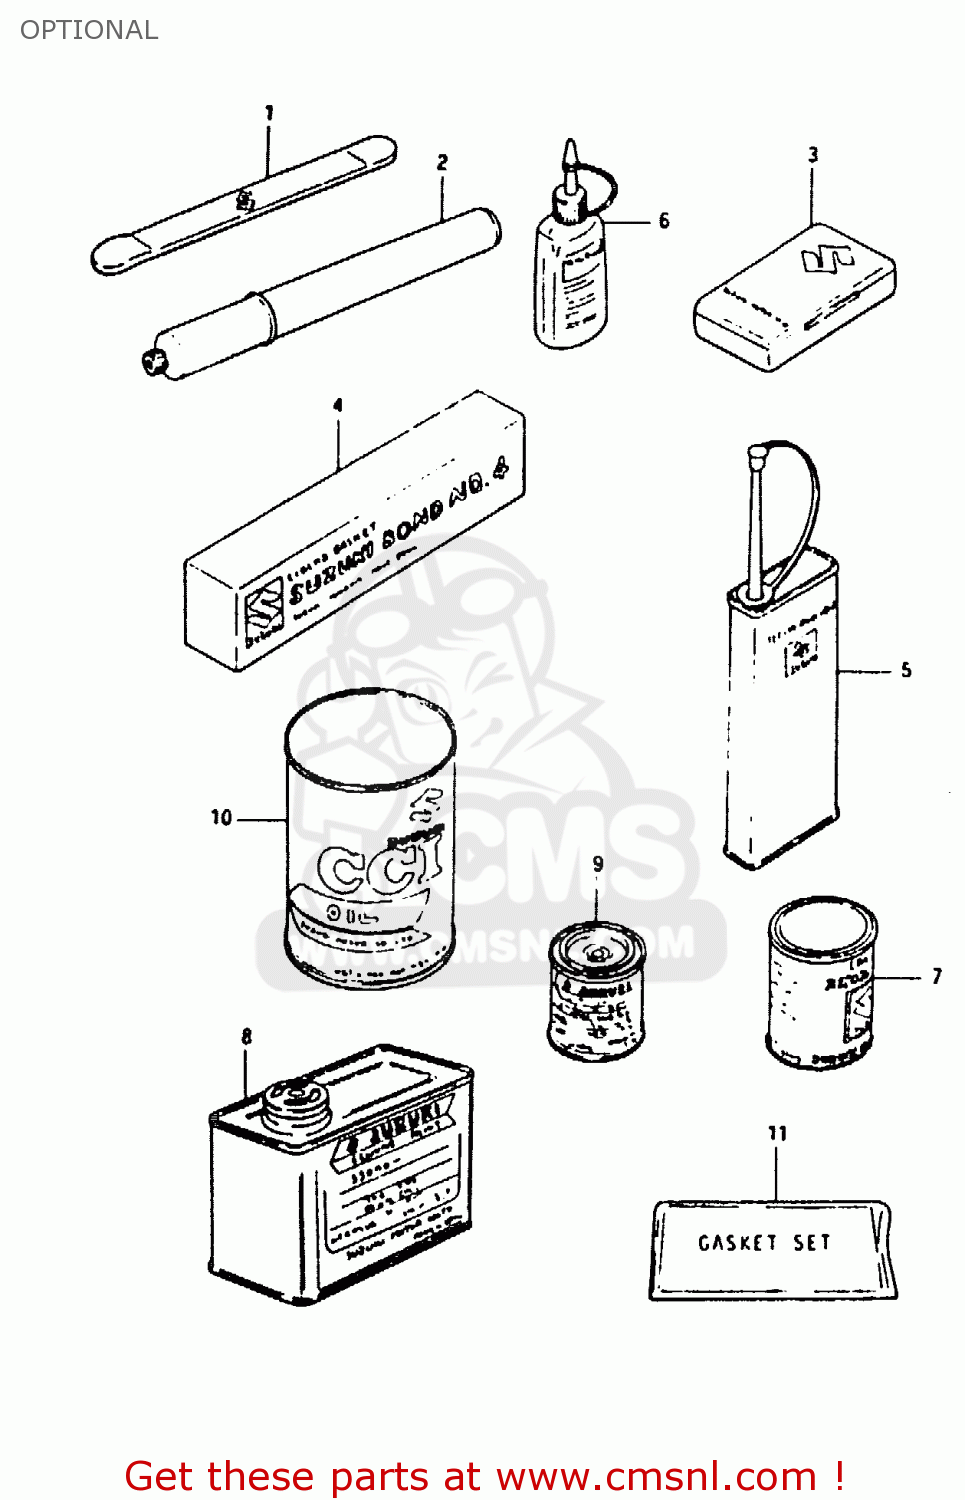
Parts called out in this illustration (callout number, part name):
1	LEVER,TIRE
2	INFLATOR, AIR
3	TUBE REPARING TOOL
4	BOND 1104
5	THREAD LOCK NO.1401 CLEAR 200G
6	THREAD LOCK NO
7	GREASE(C)EP2 LITHIUM 150G
8	PAINT (BLACK)
9	PAINT,BLACK
10	CCI OIL
11	GASKET SET (MCA)
